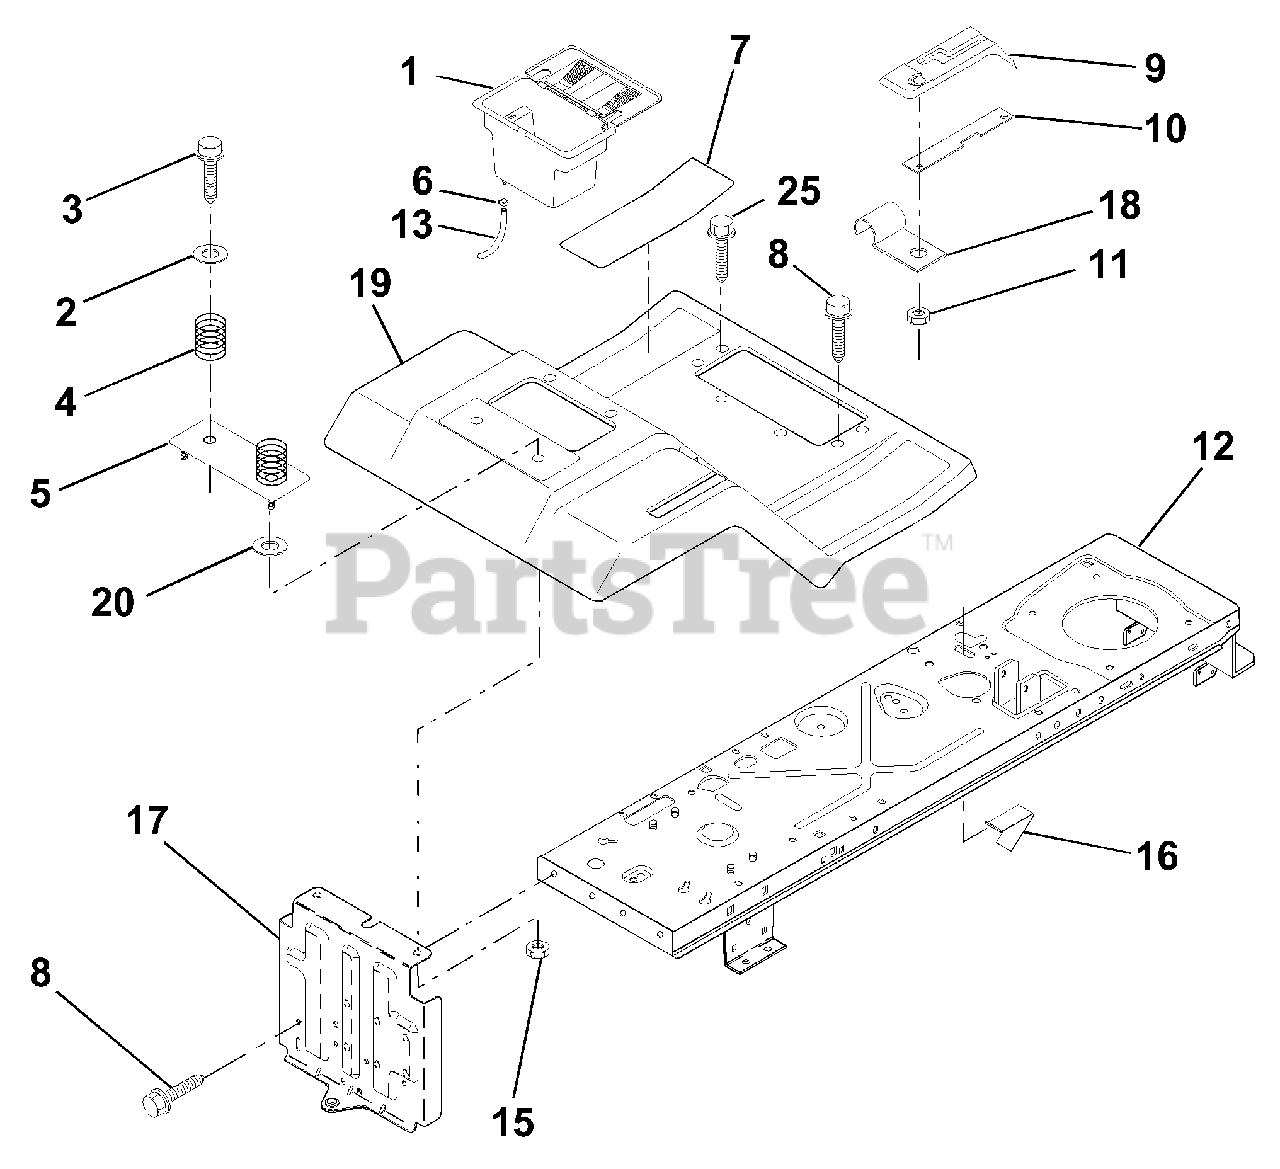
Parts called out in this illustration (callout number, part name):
1	Case, Battery
2	Washer 13/32 x 1-1/4 x 12 Ga.
3	Screw, Hex Wsh. Thrdrol 3/8-16 x 3/4
4	Spring, Compression, Seat
5	Plate, Asm. Battery
6	Clamp, Hose
7	Pad, Footrest
8	Screw Thdrol 5/16-18 x 3/4
9	Console, Shift Control
10	Bar, Shift Lock
11	Nut, Self-Threading, Wsher Hd 3/16
12	Assembly, Frame
13	Tube, Battery Drain
15	Nut, Keps 1/4-20 UNC
16	Switch Actuator
18	Clip, Insulated
19	Fender/Footrest
20	Washer 9/32 x 7/8 x 13 Ga.
25	Scr-Hx Wsh Thd Rol 5/16-18 x 1
